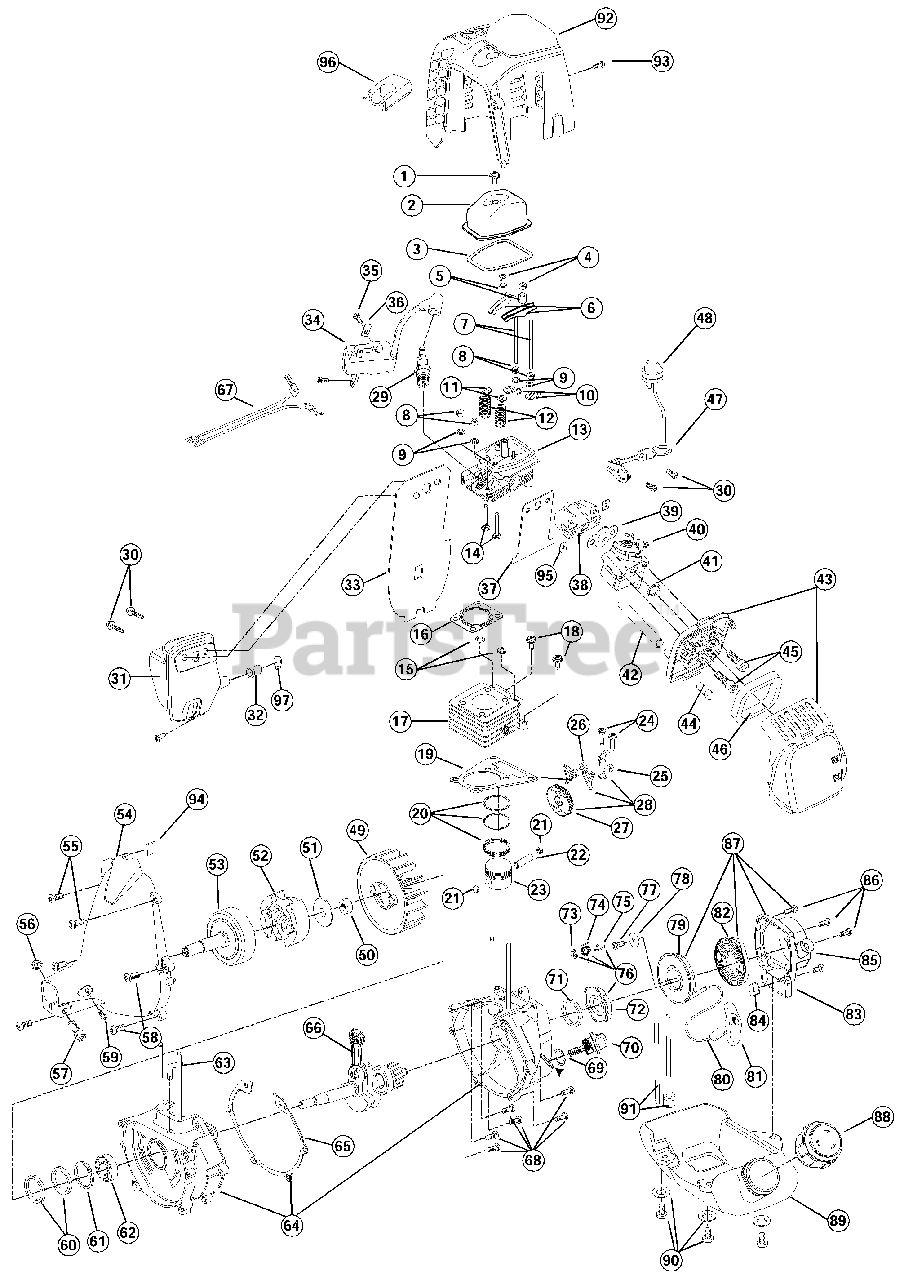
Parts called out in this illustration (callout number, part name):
1	Valve Cover Screw
2	Valve Cover
3	Valve Cover Gasket
4	Rocker Adjustment Nut
5	Rocker Arm Pivot
6	Rocker Arm
7	Push Rod
8	Hex Nut
10	Push Rod Guide
11	Valve Spring Retainer
12	Valve Spring
13	Cylinder Head w/Valve Seal (includes 10-14)
16	Cylinder Head Gasket
17	Cylinder
18	Screw (M5 x 18.7mm)
19	Cylinder Gasket
20	Piston Ring Set
21	Wrist Pin Button
22	Wrist Pin
23	Piston
24	Cam Bracket Screw
25	Cam Bracket
26	Cam Follower
27	Cam Gear
28	Cam Bracket Assembly (includes 24-27)
29	Spark Plug
30	Muffler Mounting Screw
31	Muffler
32	Spark Arrestor Screen
33	Muffler Gasket
36	Ground Tab
37	Insulator Gasket
38	Insulator
39	Carburetor Gasket
40	Carburetor
41	O-Ring, Carburetor
42	Breather Hose
43	Air Cleaner Assembly
44	Breather assembly
46	Air Filter
47	Throttle Cable Bracket
48	Primer and Line Assembly
49	Flywheel
51	Clutch Washer
53	Clutch Drum
54	Clutch Housing
55	Screw
57	Engine Bolt
58	Screw
59	Anti-Rotation Screw
60	Oil Seal
61	Snap Ring
62	Bearing
63	90? Elbow
64	Crankcase (includes 65 & 68)
65	Crankcase Gasket
66	Crankshaft
67	Lead Wire
69	O-Ring
70	Oil Cap Dipstick (includes 69)
71	Oil Seal
72	Pulley with Nut
73	Retaining Ring
75	Ratchet
76	Pulley Assembly (includes 72-75)
79	Recoil Pully
81	Pull Handle
82	Recoil Spring
83	Recoil Case
84	Square Nut
85	Rope Guide
87	Recoil Case Assembly (includes 79-86)
88	Fuel Cap
89	Fuel Tank
90	Screw with Washer
91	Fuel Line Assembly
92	Engine Cover
94	Wire Grommet
96	Spark Plug Cover
97	Spark Arrestor Clamp
98	Screw
